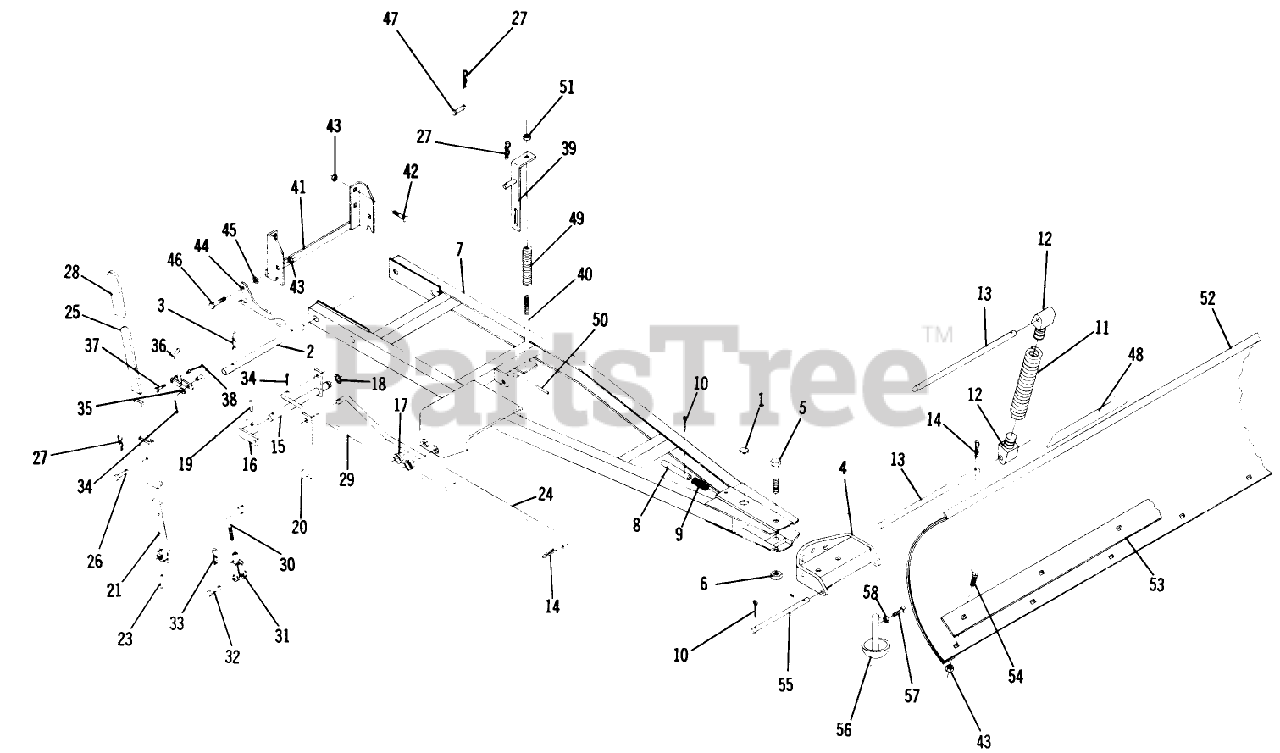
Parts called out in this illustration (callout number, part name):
1	PLUG
2	Mounting Shaft
3	Hairpen
4	Sector and Channel
5	Bolt Hex 3/4-16 x 3 3/4
6	Nut-3/4-16 E.S.
7	Frame Assembly
8	Index Pin
9	SPRING-COMPRESSION
10	Cotter Pin
11	Spring
12	Lug
13	ROD-TRIP RETURN
14	Hairpin
15	Bushing
16	Sat Collar
17	BUSHING
18	Snap Ring
19	SPIROL PIN 3/8X1 3/4
20	Assembly-Blade Index Arm
21	Assembly-Handle Bar
22	3/8-16 Jam Nut
23	SPIROL PIN 3/8X1 1/2
24	Blade Control Rod
25	HANDLE ASM
26	Clevis Pin
27	Hairpin
28	GRIP
29	ROD LOWER INDEX
30	ROD UPPER INDEX
33	Hairpin
34	Cotter Pin
35	Washer
36	Assembly Index Lever
37	Bolt-Hex 1/4-20
38	Nut-Nylok
39	Assembly-Lift Bar
40	Assembly Lift Rod
41	Breather
42	Bolt-Carr. 3/8-16 x 3 1/2
43	3/8-16 E.S.
44	Latch Hitch
45	Washer
46	Bolt, 3/8-16 x 1 1/2
47	Pin Clevis
48	DECAL-WHEEL HORSE
49	SPRING
50	Spirol Pin
51	Nut-ES 1/2-13
52	Assembly Blade-54"
52	Blade Assembly
53	Plate-Blade Edge
53	PLATE-BLADE EDGE
54	Bolt-3/8-16 x 3/4
55	ROD-LOWER
56	Skid
57	Set Screw-3/8-16 x 1
